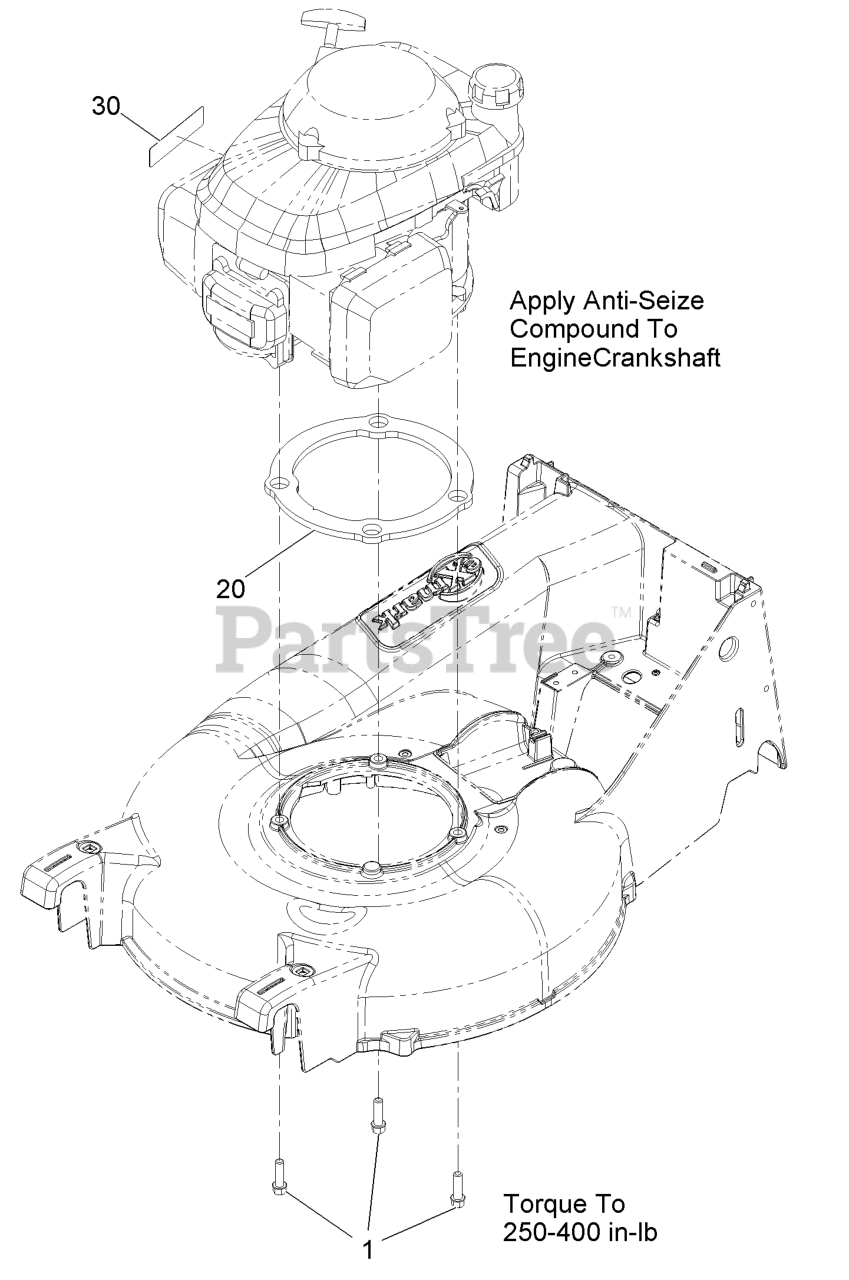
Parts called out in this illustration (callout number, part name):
1	SCREW-TAPTITE
20	GASKET,DECK
30	DECAL-ARRESTER, SPARK
